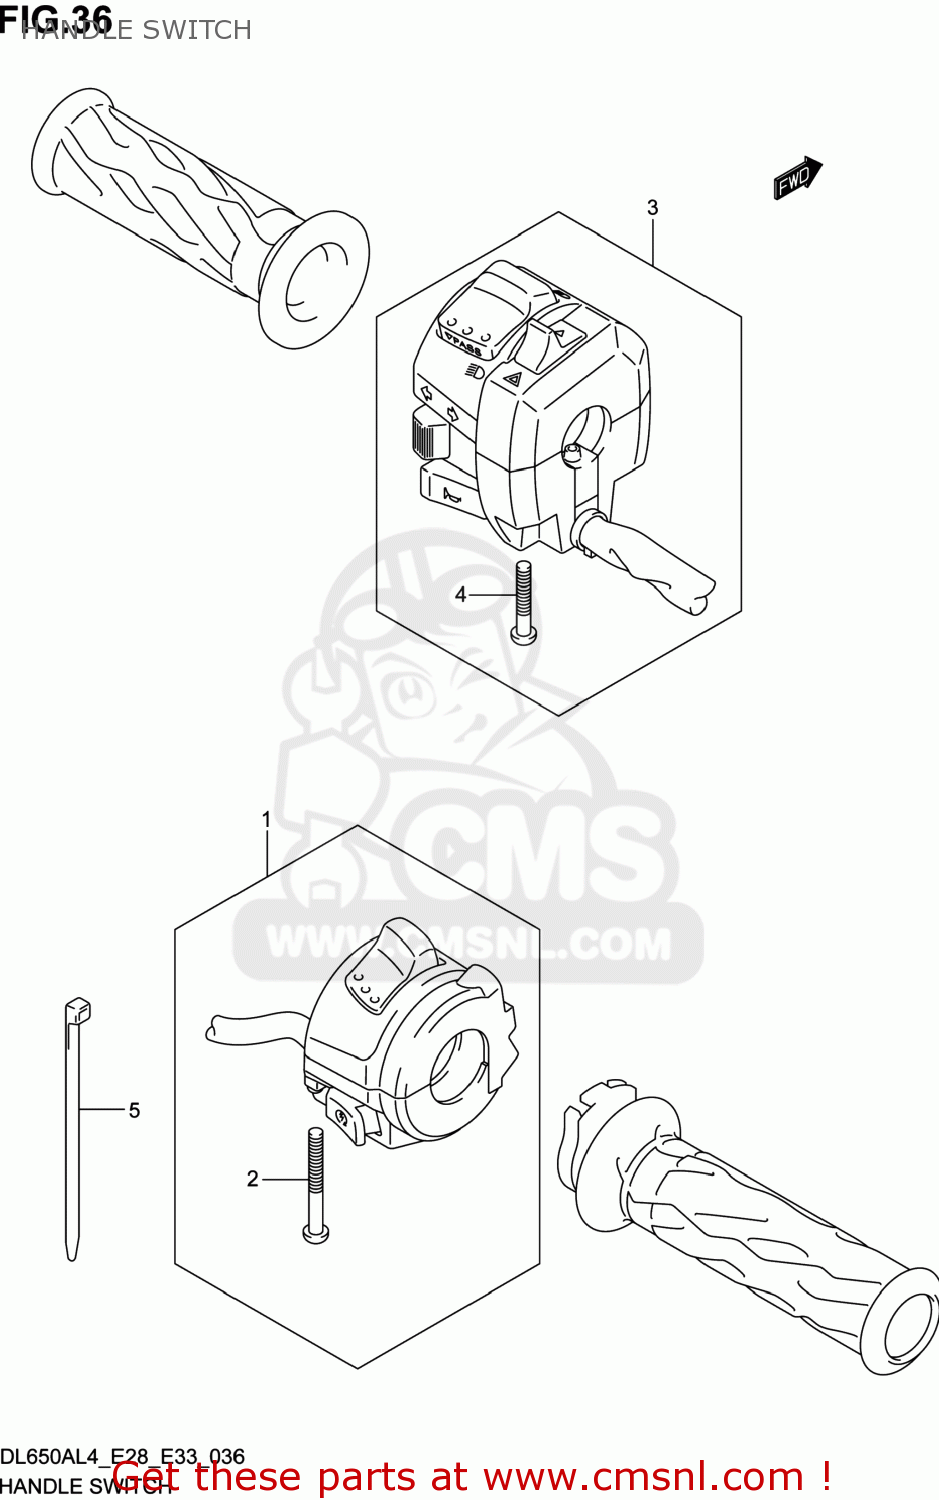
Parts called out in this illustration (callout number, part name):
1	SWITCH ASSY,HANDLE,R
2	SCREW
3	SWITCH ASSY,HANDLE,L
4	SCREW
5	CLAMP(L:145)
